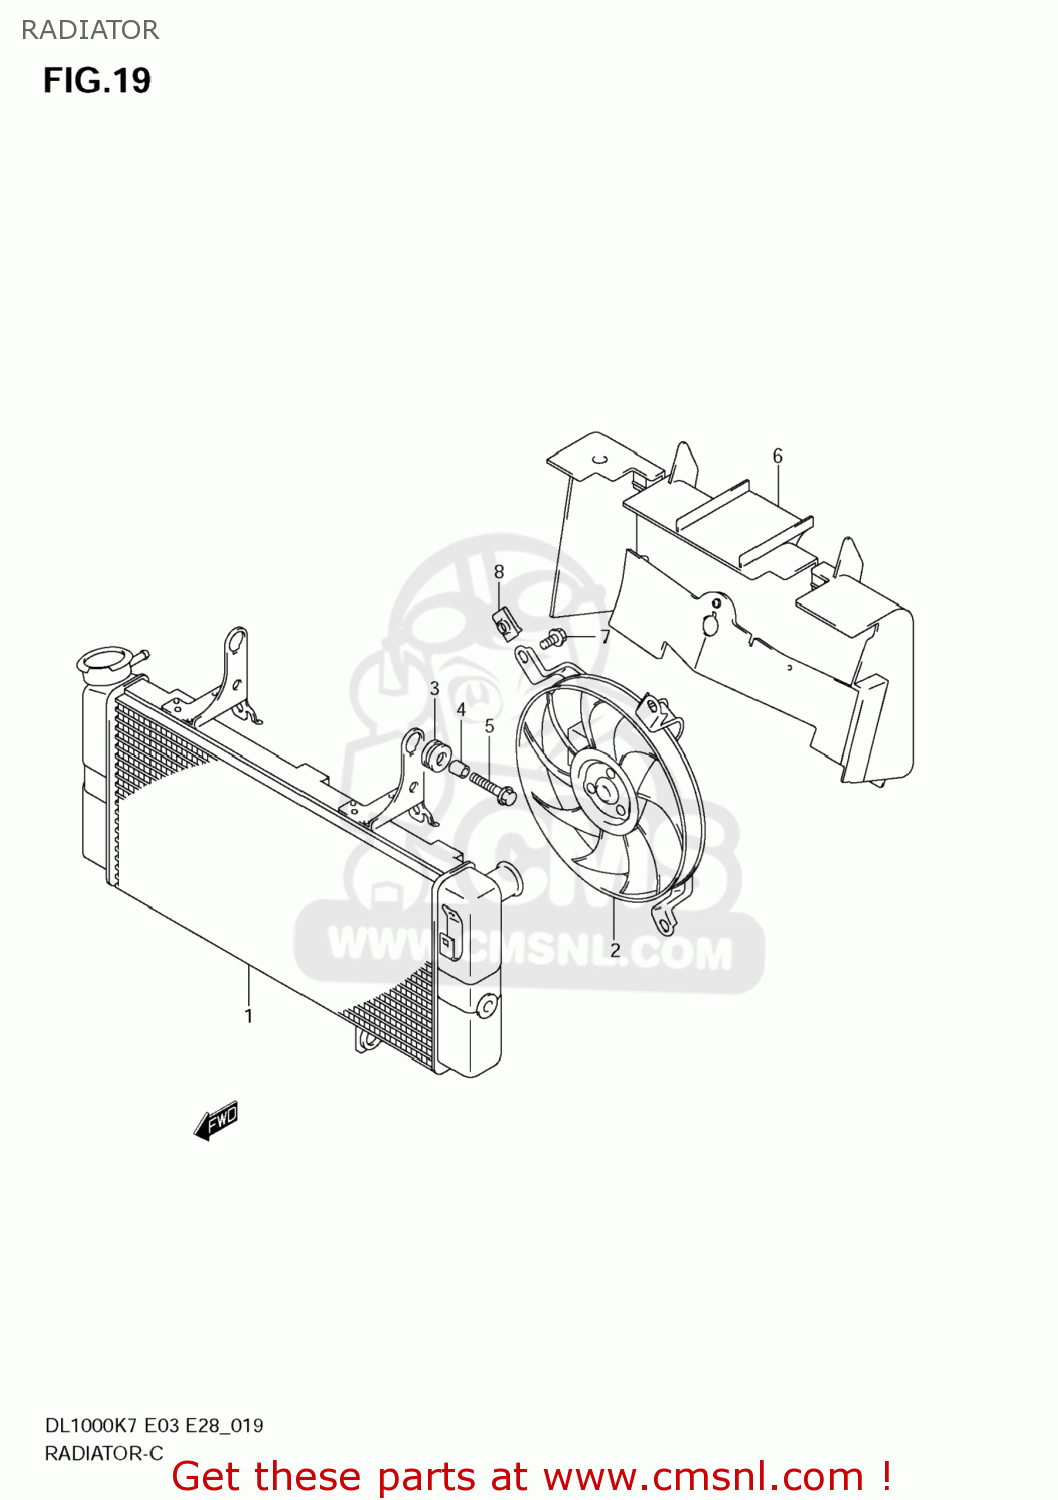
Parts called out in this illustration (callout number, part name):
1	RADIATOR ASSY,WATER
2	FAN ASSY,RADIATOR
3	CUSHION
4	SPACER(6.5X10X12)
5	BOLT(6X25)
6	SHIELD,RADIATOR HEAT
7	BOLT,FAN ASSY
8	NUT,FAN ASSY
